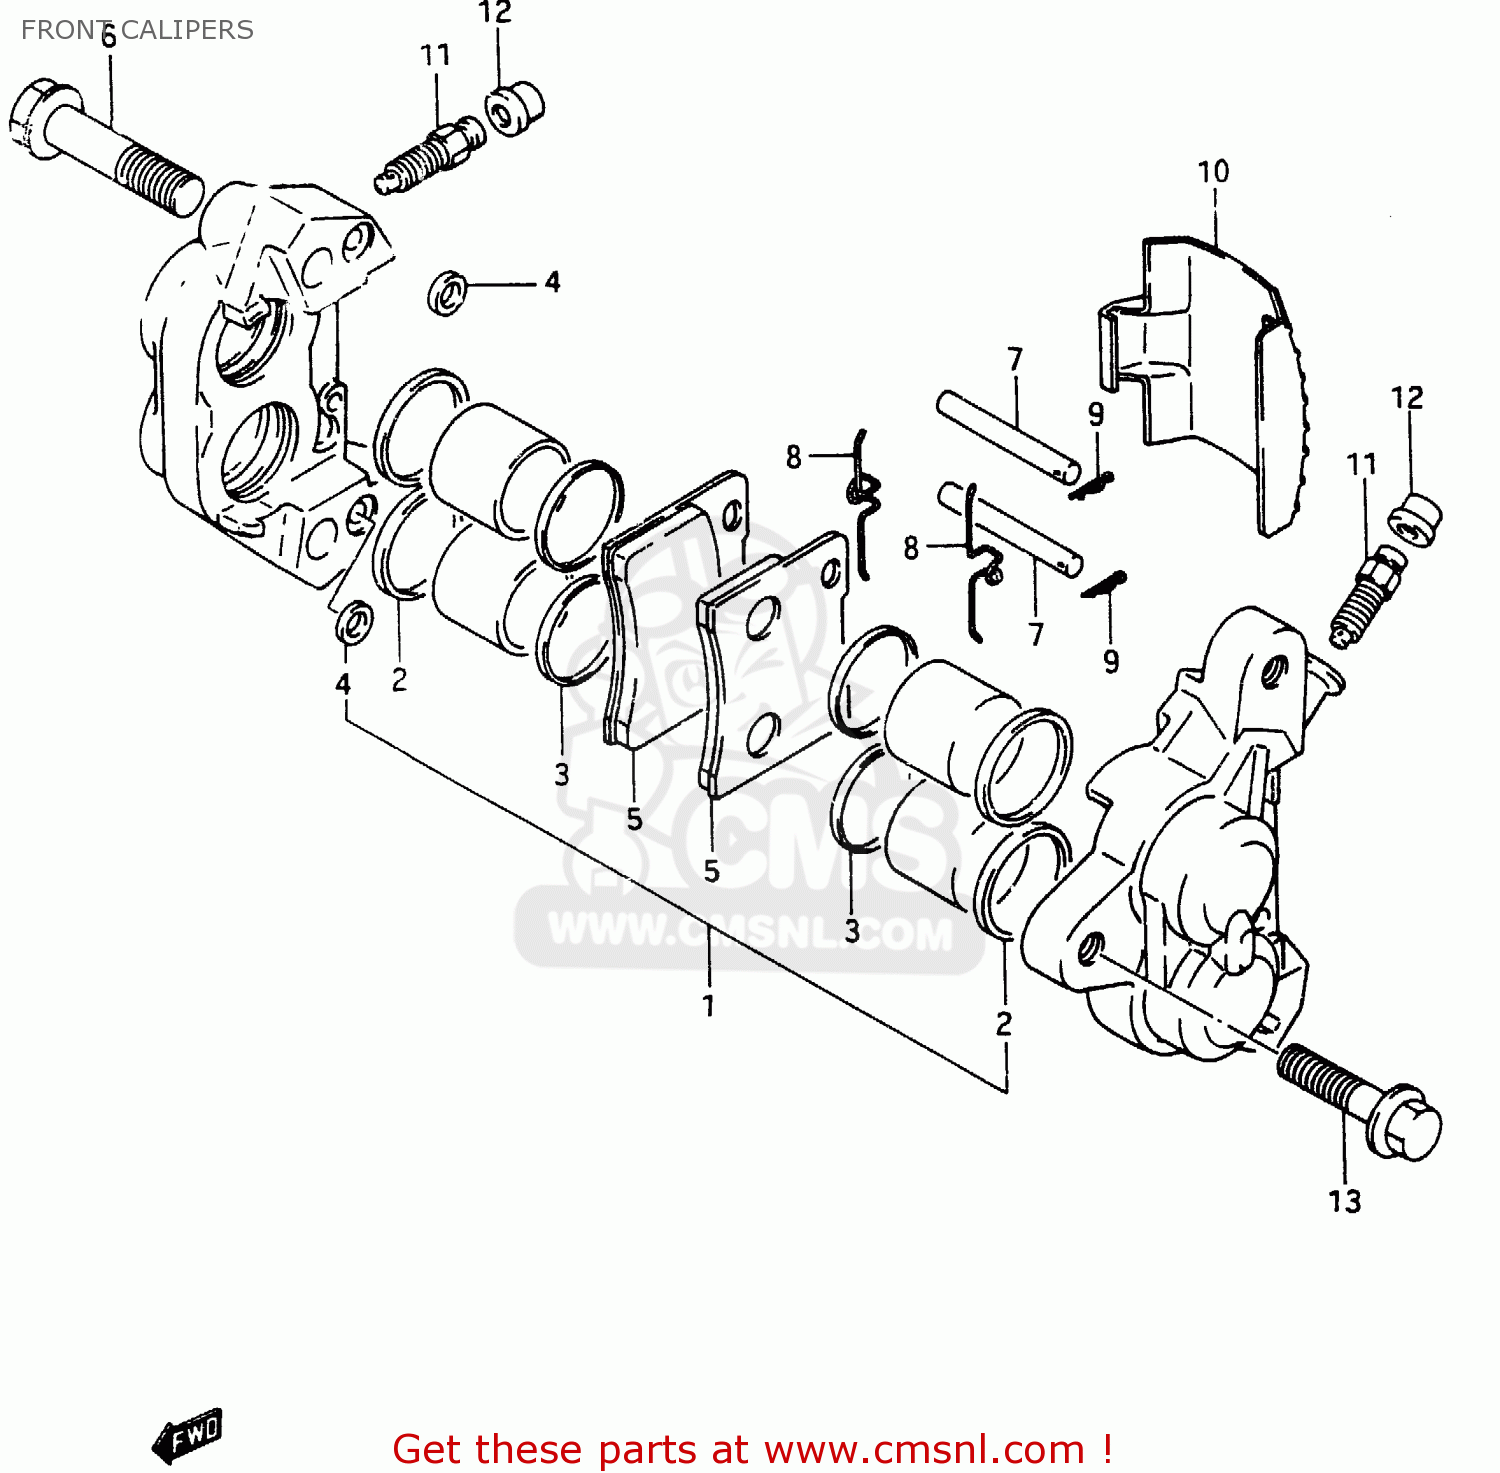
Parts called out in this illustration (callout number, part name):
1	PISTON&PAD SET
2	SEAL,PISTON
3	SEAL,WIPER
4	SEAL,JOINT
5	PAD,BRAKE (NAS)
6	BOLT,HOUSING
7	PIN,PAD
8	SPRING
9	CLIP,PAD PIN
10	COVER,CALIPER
11	BLEEDER
12	CAP,BREATHER
13	BOLT
